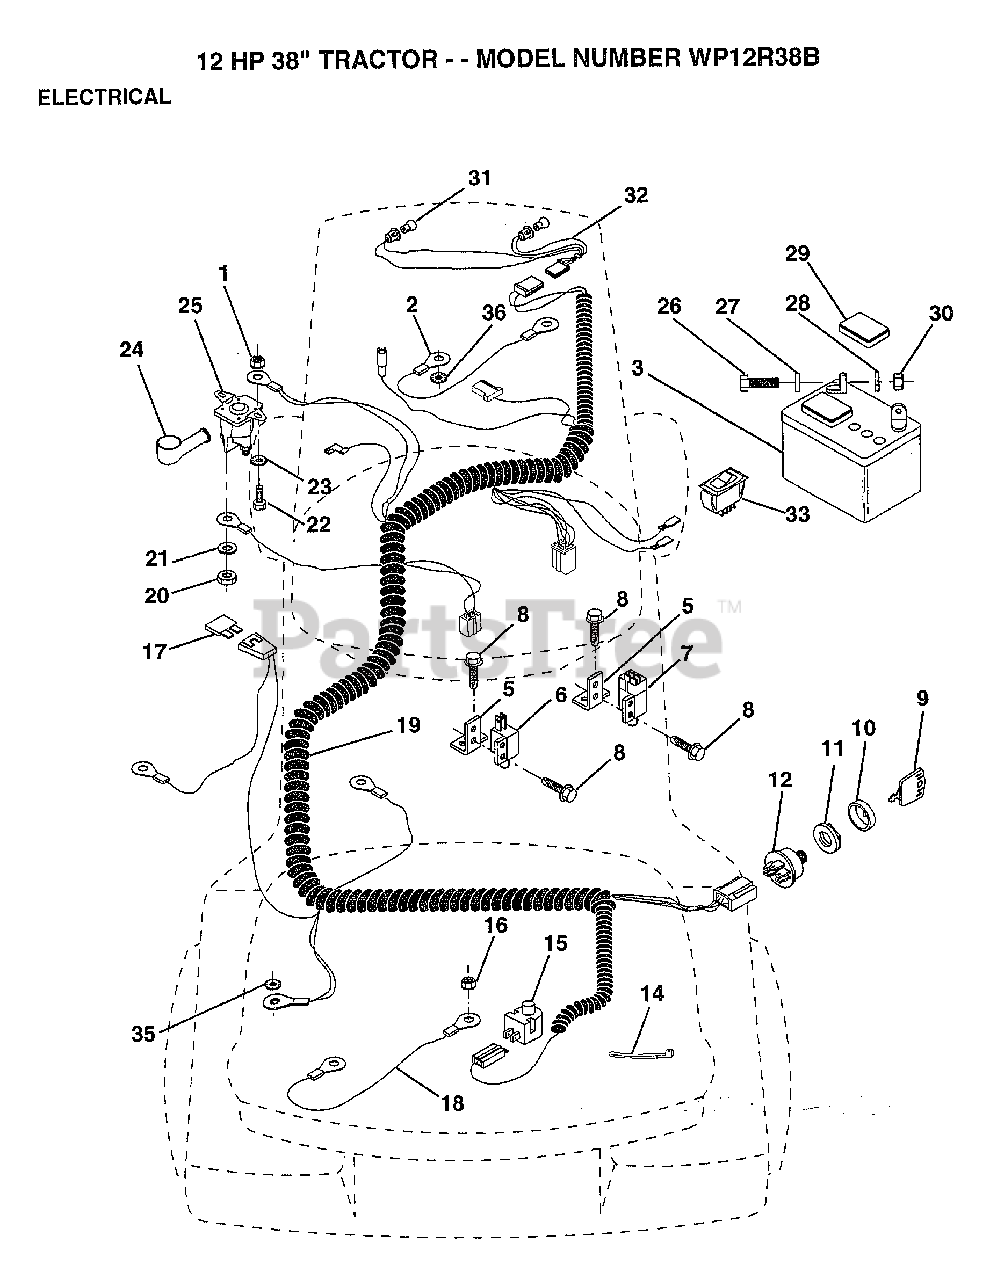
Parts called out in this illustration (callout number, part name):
1	NUT
2	CABLE ASM.
5	BRACKET LT
6	SWITCH-INTER. GT
7	SWITCH INTERLOCKT
8	SCREW
9	KEY
11	NUT IGNITION
14	WIRE TIE
15	SWITCH SEAT
17	FUSE HYT
18	CABLE ASSY
20	NUT
22	BOLT
26	BOLT LT
27	WASHER
28	LOCKWASHER
29	"CAP,BATTERY "
33	SWITCH LT
35	LOCKWASHER
36	LOCKWASHER
